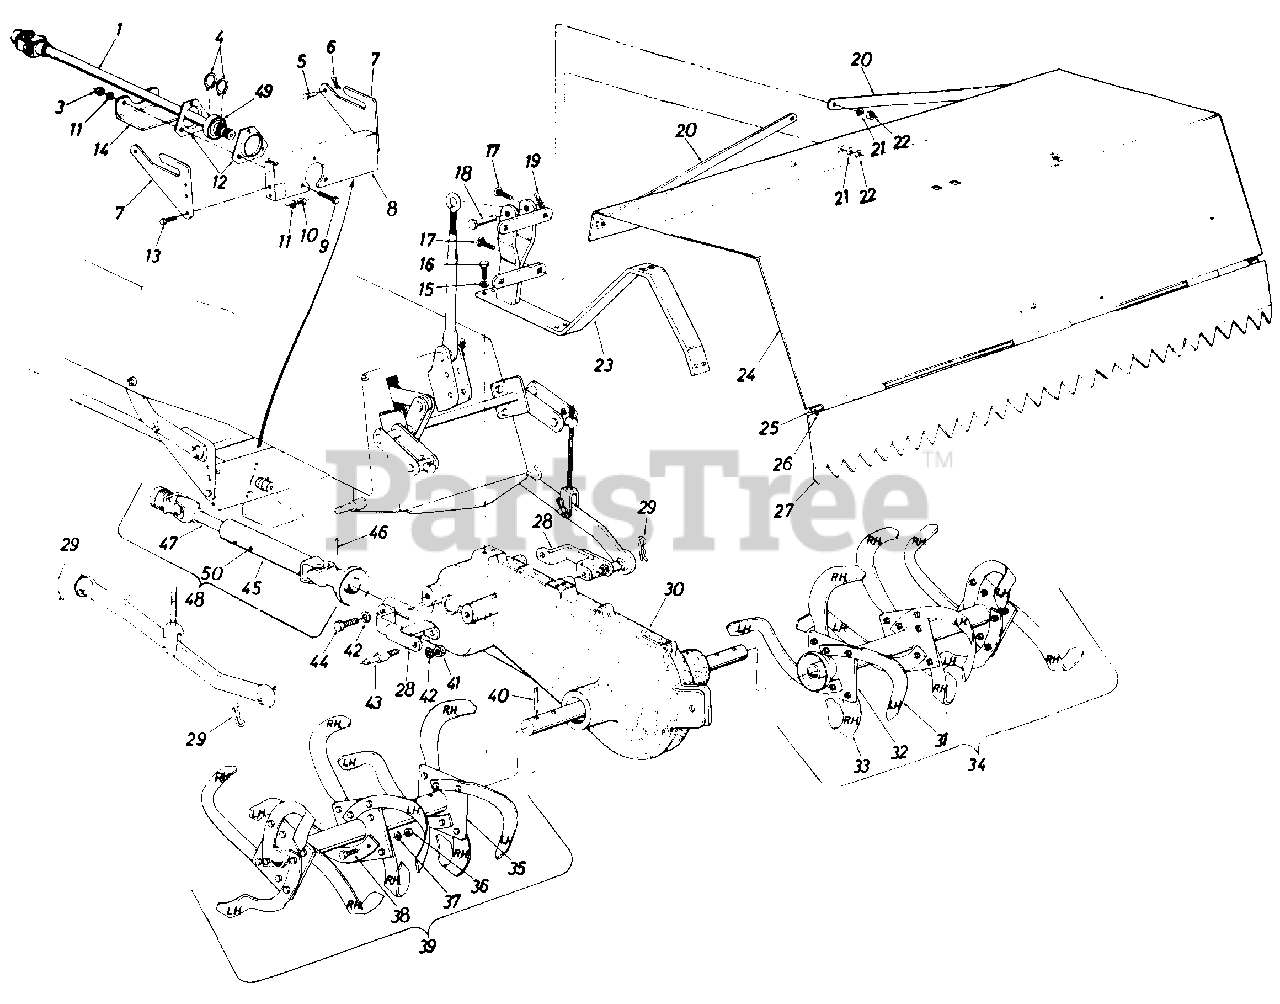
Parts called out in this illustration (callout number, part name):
1	Universal Drive Shaft Ass'y.
3	Hex Nut 5/16-18 Thd.*
4	Retaining Ring 1.00" Dia. Shaft
5	Clevis Pin
6	Internal Cotter Pin
7	Hanger Bracket
8	Drive Shaft Brg. Support Bracket
9	Carriage Bolt 5/16-18 x 1.00" Lg.*
10	Hex Nut 5/16-24 Thd.*
11	L.-Wash. 5/16" Scr.*
12	Flangette Bearing
13	Hex Scr. 5/16-24 x .75" Lg.*
14	Bearing Brk't. Guard
15	L.-Wash. 1/2" Scr.*
16	Hex Scr. 1/2-13 x 1.25" Lg.*
17	Carriage Bolt 5/16-18 x 1.00 Lg.*
18	Clevis Pin 5/8" Dia. x 2.4" Lg.
19	Internal Cotter Pin 5/8" Dia.
20	Tiller Cover Strap
21	L.-Wash. 5/16" Scr.*
22	Hex Nut 5/16-18 Thd.*
23	Cover Brk't. Ass'y.
24	Tiller Cover Ass'y.
25	Cover Flap Rod
26	Cotter Pin 1/8" Dia. x 1.00 Lg.*
27	Cover Flap Ass'y.
28	Tiller Pivot Bracket Ass'y.
29	Internal Cotter Pin 5/8" Dia.
30	Gear Box Ass'y.-Comp.
31	14" Tine-L.H.
32	Mounting Adapter-R.H.
33	14" Tine-R.H.
34	Right Hand Tine Ass'y.-Comp.
35	Mounting Adapter-L.H.
36	Hex Nut 3/8-24 Thd.*
37	L.-Wash. 3/8" Scr.*
38	Hex Scr. 3/8-24 x 1.25" Lg.*
39	Left Hand Tine Ass'y.-Comp.
40	Spring Pin Spirol 3/8" Dia. x 2.00" Lg.
41	Hex Cent. L-Nut 5/8-18 Thd.
42	L.-Wash. 5/8" Scr.*
43	Link Clevis Pin
44	Hex Scr. 5/8-11 x 1.50" Lg.*
45	Female Universal Half
46	Spring Pin Spirol 5/16" Dia.
47	Male Universal Half
48	Universal Drive Shaft Comp.
49	Ball Bearing
50	Spring Pin Spirol 1/4" Dia. x l.OO" Lg.
